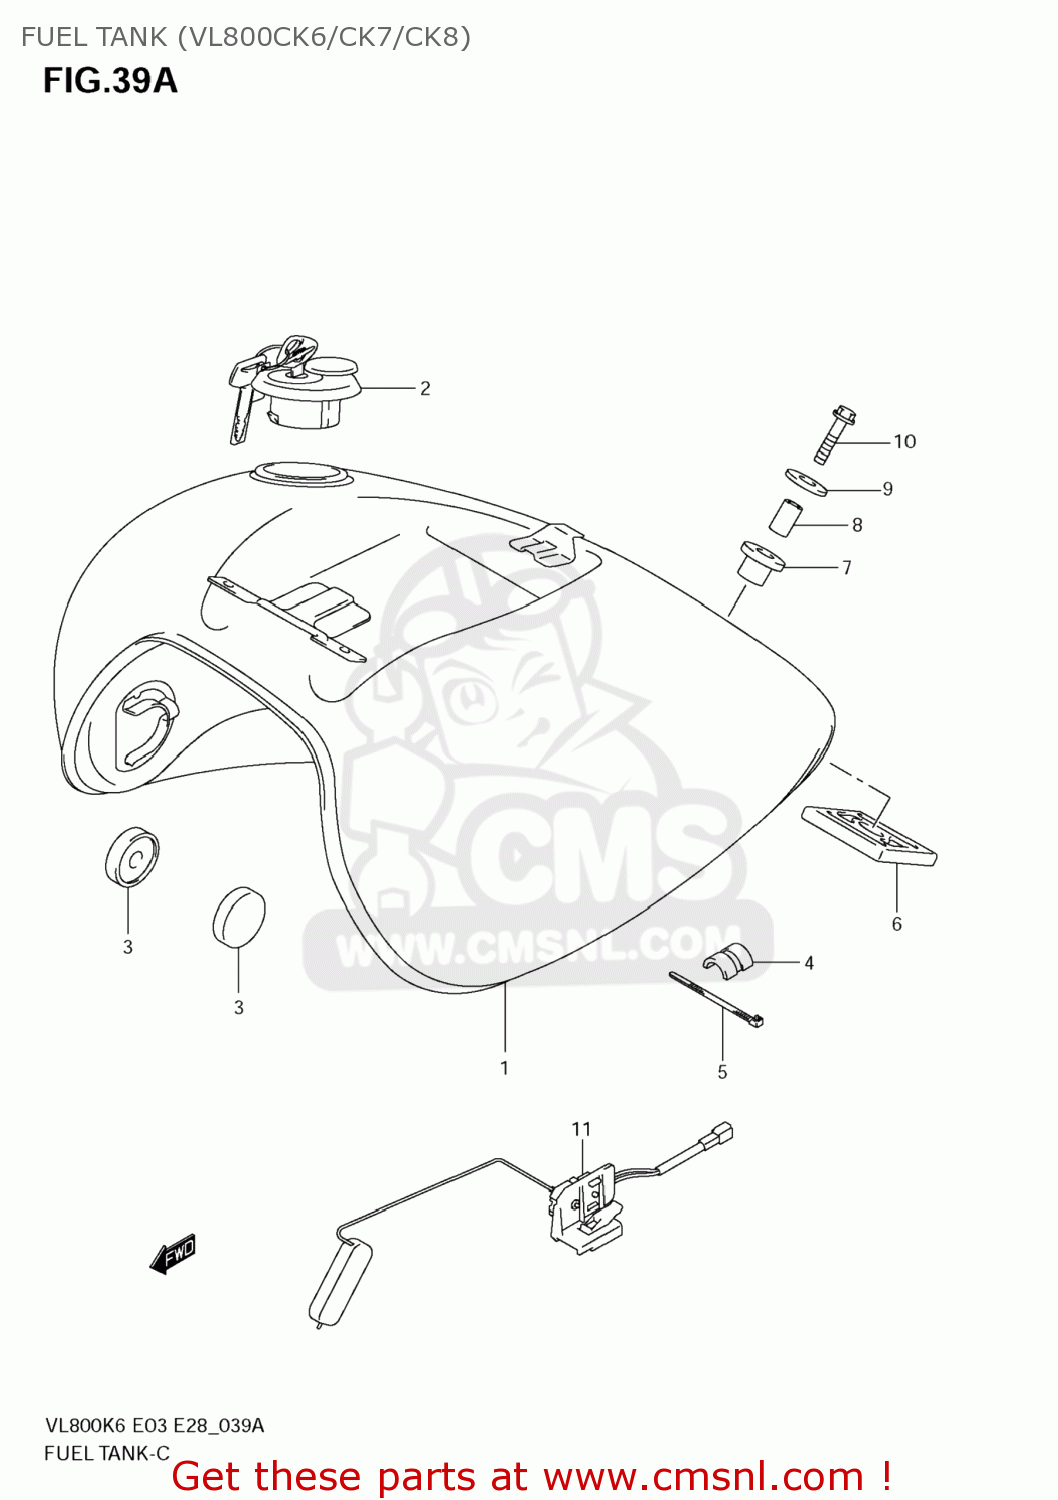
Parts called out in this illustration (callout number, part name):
1	TANK ASSY,FUEL(WHITE)
2	CAP SET,FUEL TANK
3	CUSHION
4	CUSHION,FUEL TANK LWR
5	CLAMP(L:250)
6	CUSHION,FUEL TANK RR LWR
7	CUSHION,FUEL TANK RR UPR
8	SPACER (8.2X12.5X23.5)
9	WASHER (8.5X33X1.6)
10	BOLT
11	GAUGE ASSY,FUE
